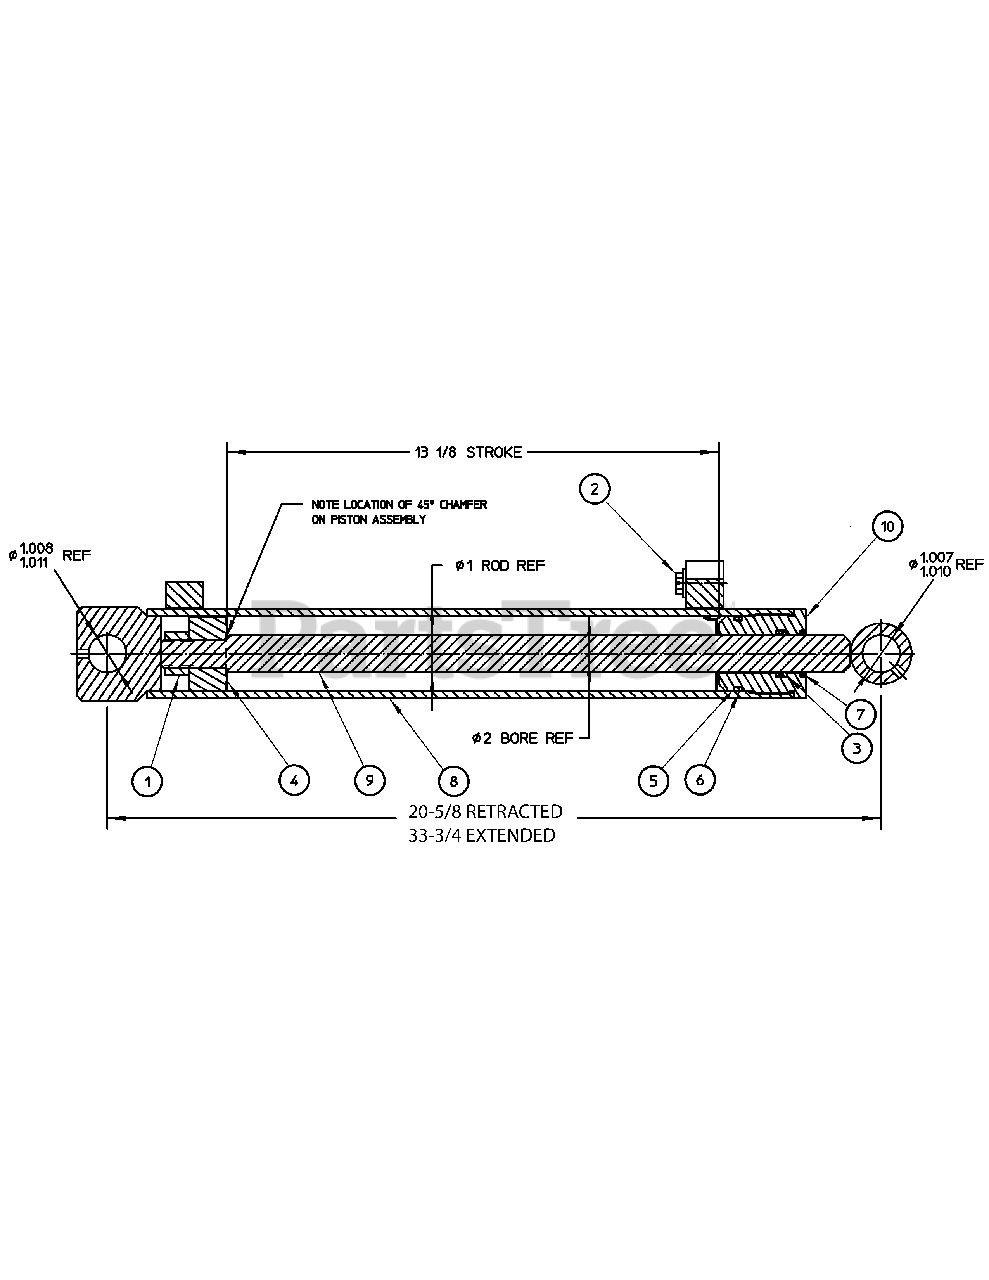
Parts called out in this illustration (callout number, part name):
1	Nut, 3/4 NF Nylok
2	Port Plug
3	Rod Seal*
5	O-Ring*
6	Back-Up Ring*
7	Wiper Seal*
8	Cylinder Tube Weldment
9	Piston Rod Weldment
10	Threaded Gland
